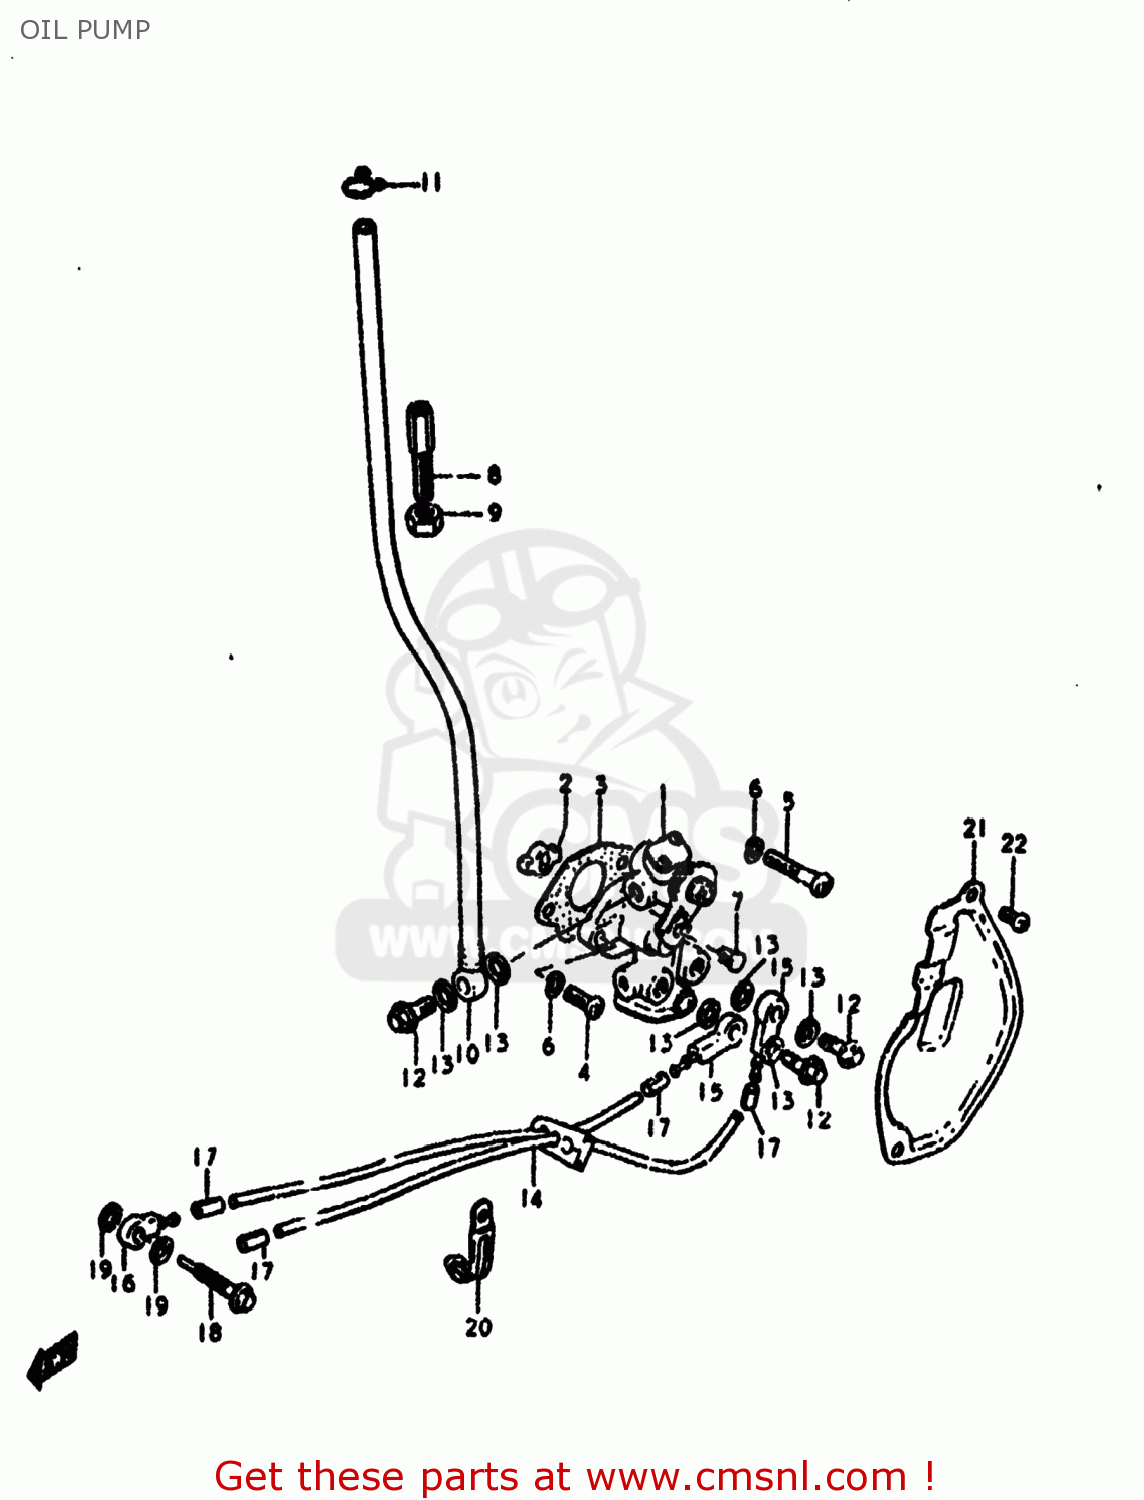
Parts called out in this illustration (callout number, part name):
1	PUMP ASSEMBLY,OIL
2	PIECE,OIL PUMP DRIVE
3	GASKET,OIL PUMP (MCA)
4	SCREW
5	SCREW
6	LOCK WASHER
7	TERMINAL,CABLE
8	BOLT
9	NUT
10	HOSE,OIL NO.1
11	CLIP
12	UNION BOLT
13	GASKET(6.2X11X1).2 (NAS)
14	HOSE,OIL NO.2
15	VALVE,CHECK
16	UNION
17	CLIP
18	UNION
19	GASKET(6.2X11X1).2 (NAS)
20	CLAMP L:35
21	CAP,OIL PUMP INSPECTION
22	SCREW
